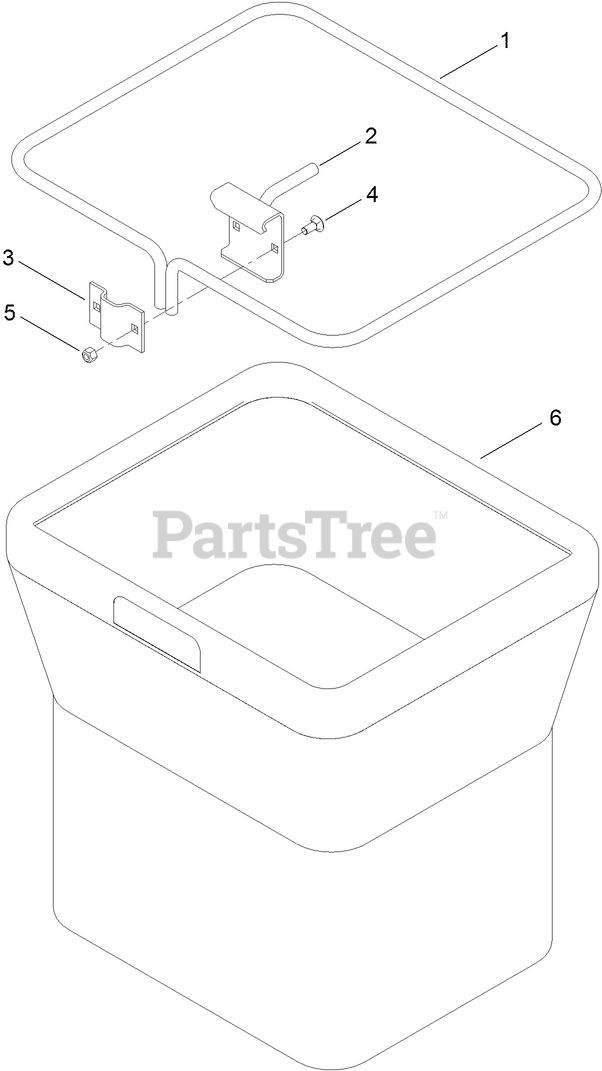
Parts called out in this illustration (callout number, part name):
1	FRAME-BAG
4	BOLT-CARR
5	NUT-LOCK, NI
6	BAG
